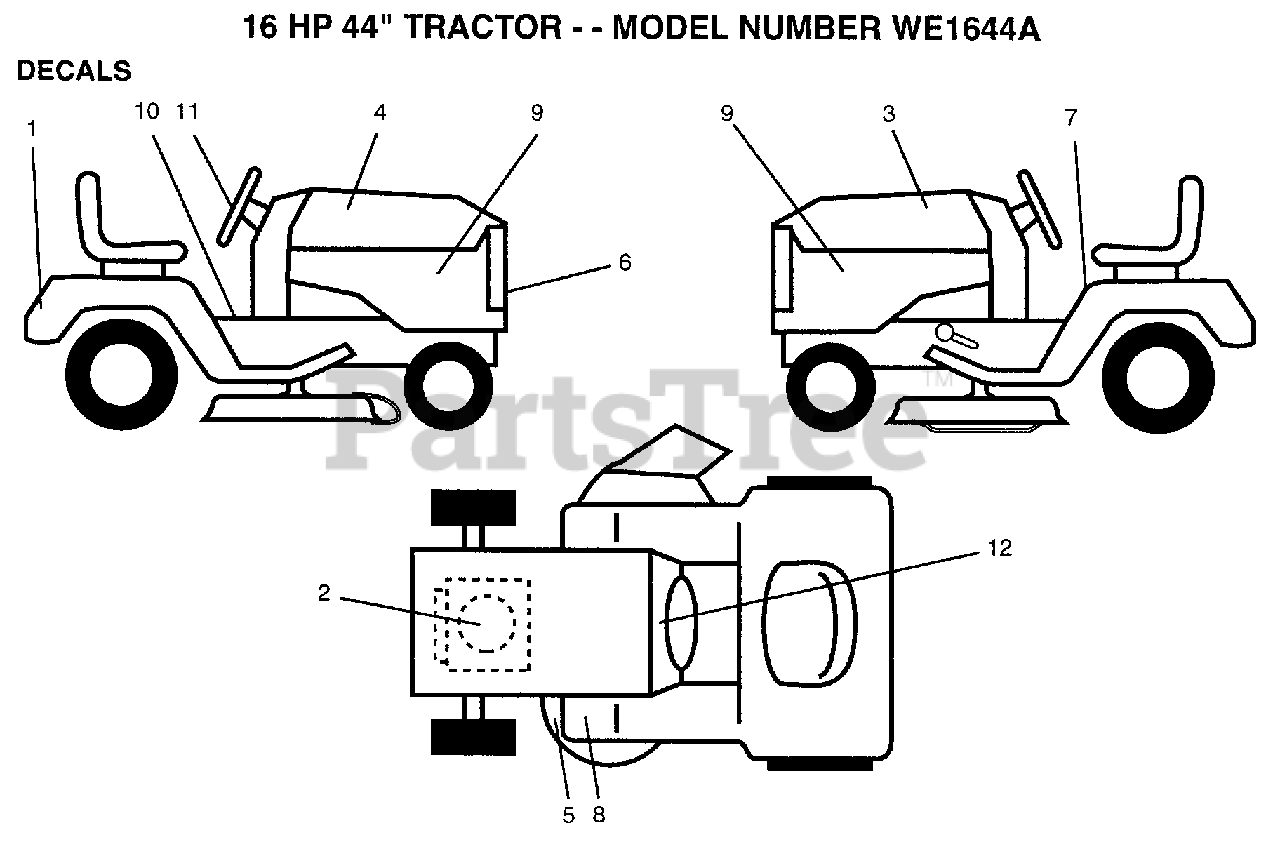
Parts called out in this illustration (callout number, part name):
1	DECAL.FENDER
2	DECAL.ENG.272090
3	DECAL.HD.WEED.LH
4	DECAL.HD.WEED.RH
5	"DECAL.V.BELT.44"""
6	DECAL.GRILL
7	DECAL CAUT FEND
8	DECAL CLUT/BRAKE
9	DECAL.PNL.SIDE.16
10	DECAL BRAK PARK
11	DECAL.WHL.STRG.
12	DECAL INST OP DAS
